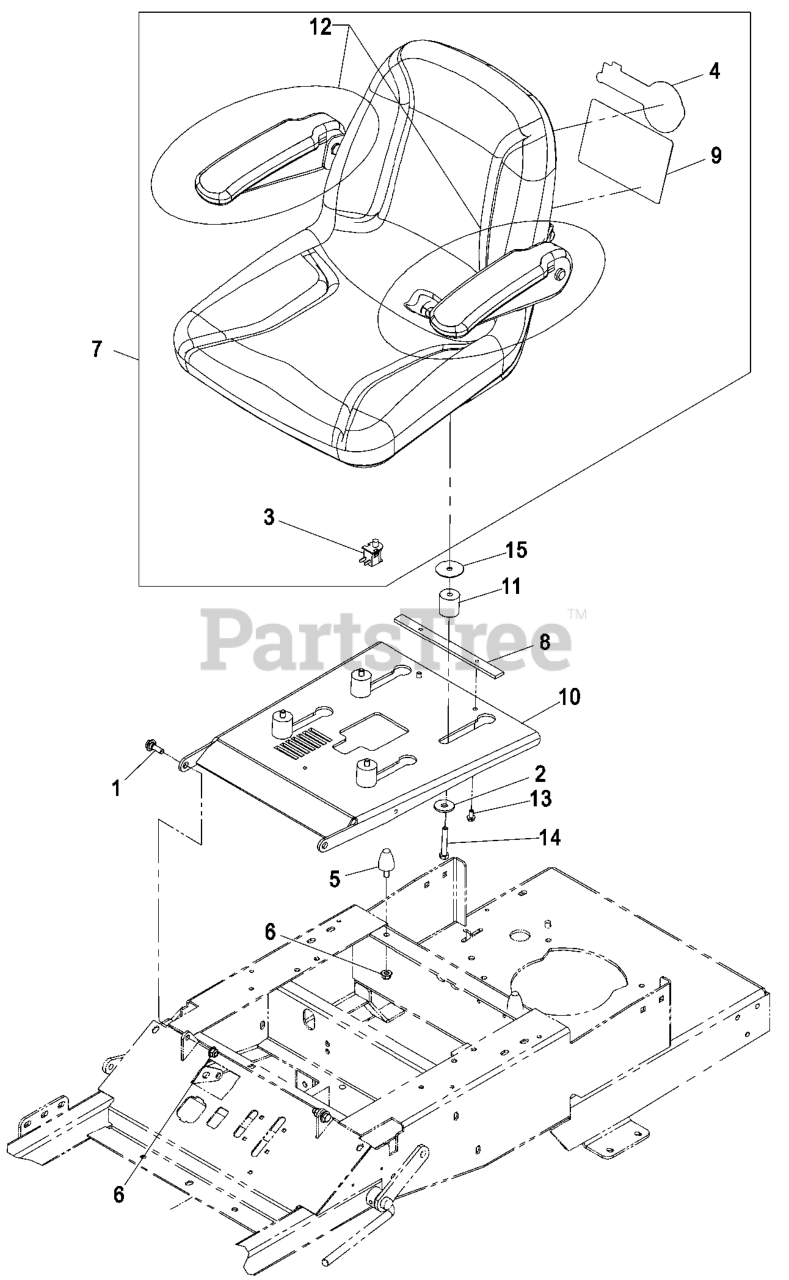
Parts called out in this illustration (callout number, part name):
1	SCREW-SHOULDER
3	SWITCH-BAIL
4	DECAL,EXMARK LOGO
5	BUMPER-SEAT
6	NUT-HF, NI
7	ASM,PHAZER SEAT W/DECALS
8	BAR-STOP, SEAT
9	DECAL,SERVICE AID PHAZER
10	BRACKET-SEAT
12	ARMREST KIT
13	SCREW-HWH
14	SCREW-HH
